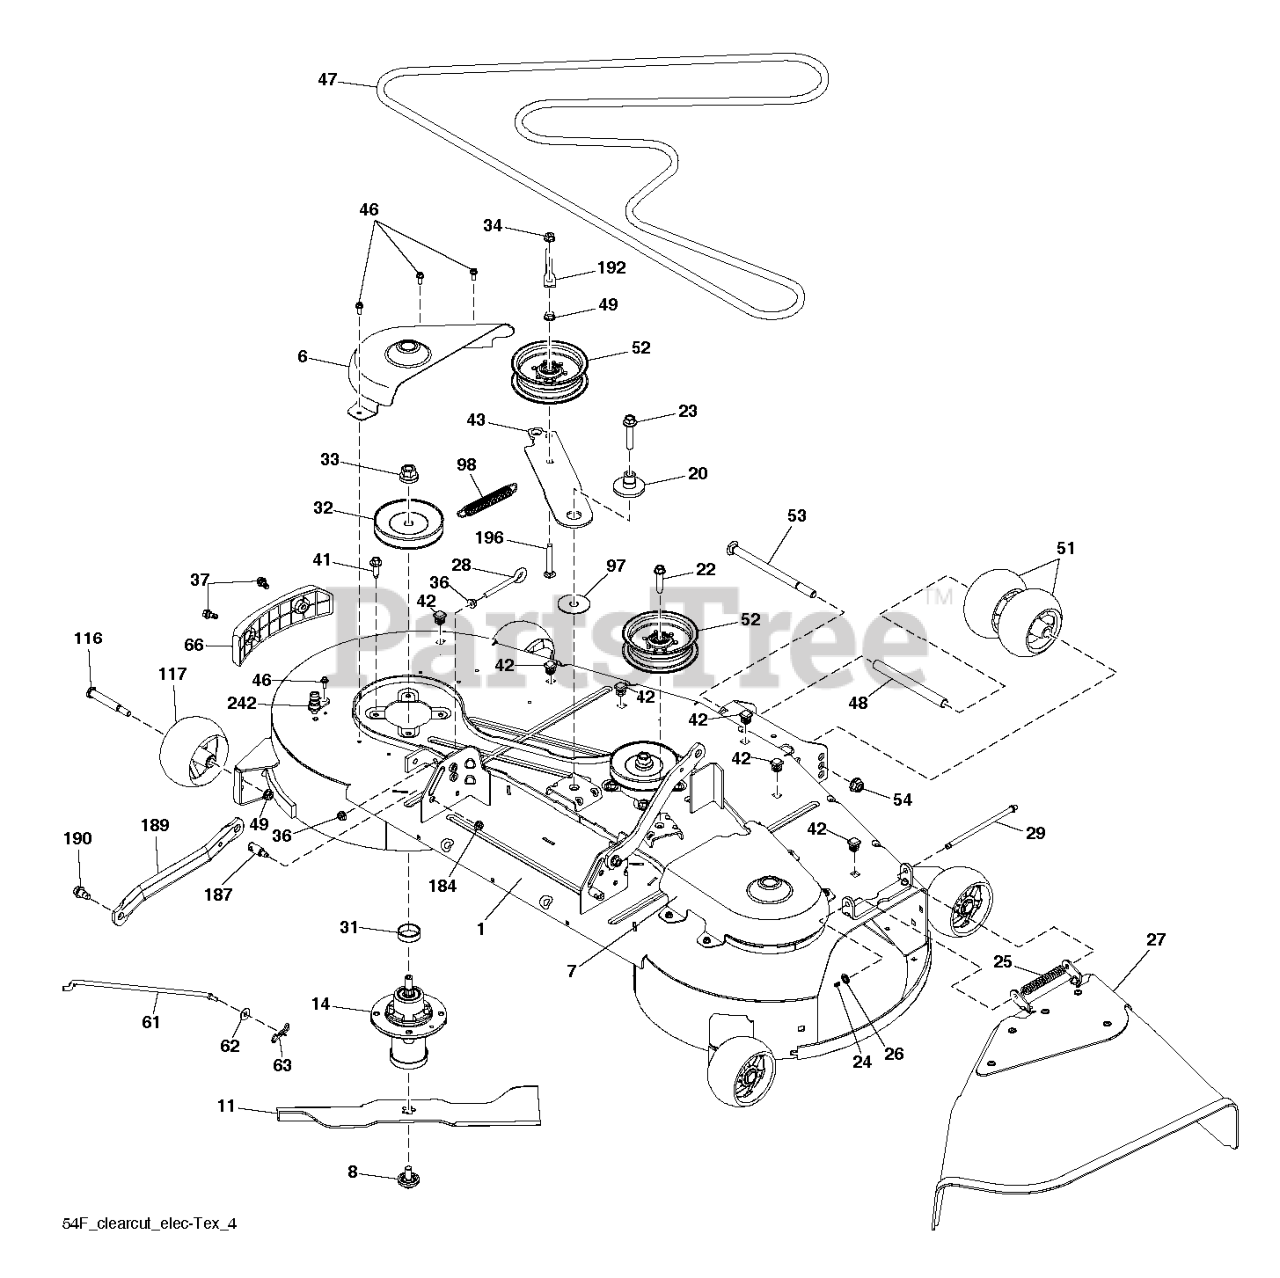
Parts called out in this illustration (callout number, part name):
1	SERVICE KIT KIT.SVC.WELDMENT.5
6	COVER 54 CLEARCUT, LH MANDREL,
7	COVER 54 CLEARCUT RH MANDREL G
8	BOLT.WASHER.ASM.7/16-2
11	BLADE CC54 PZ STYLE HI LIFT BL
14	MANDREL ASM, CAST IRON
20	SPACER.IDLER.PULLY.HUB
22	BOLT;HEX_3/8-16 X 1.78.CLRZINC
23	SCREW.7/16-14 X 2.125.WASHER
24	CAP-SLEEVE LT
25	SPRING.42.FCS.DEFLECTOR
26	NUT PUSH M
27	DEFLECTOR ASSY 54 CLEARCUT RES
28	GSPW Bolts
31	WASHER.SPACER.MANDREL
32	PULLEY/MANDREL
36	GSPW Hardware
37	SHOULDER BOLT 5/16-18TT
41	BOLT.HEX.WASHR.HED.313-18X1.19
43	ARM IDLER ARM, CLEARCUT 54 BLA
46	SCREW.1/4-20X5/8
47	BELT CLEARCUT 54, TRACTOR DECK
49	NUT LOCK FLG 3/8-16 UNC
51	ROLLER, GAUGE .635 BORN
52	PULLEY.IDLER.2006
54	NUT 1/2-13 HEX FLANGE NYLOK CL
63	PIN.COTTER.5/16.BOW TI
66	BUMPER ASSY 54 CLEARCUT TRIM S
98	SPRING.EXTN.42.FCS.TR.DECK.DRV
117	WHEEL.GAUGE.RALLY
187	STUD.W/"D"ANTI-ROTATION
189	ARM.RFIXED.MOWER.SUSPNSIONX431
190	BOLT.SHOULDER
192	KEEPER.BELT.IDLER.54"T
242	PORT.WASHOUT
